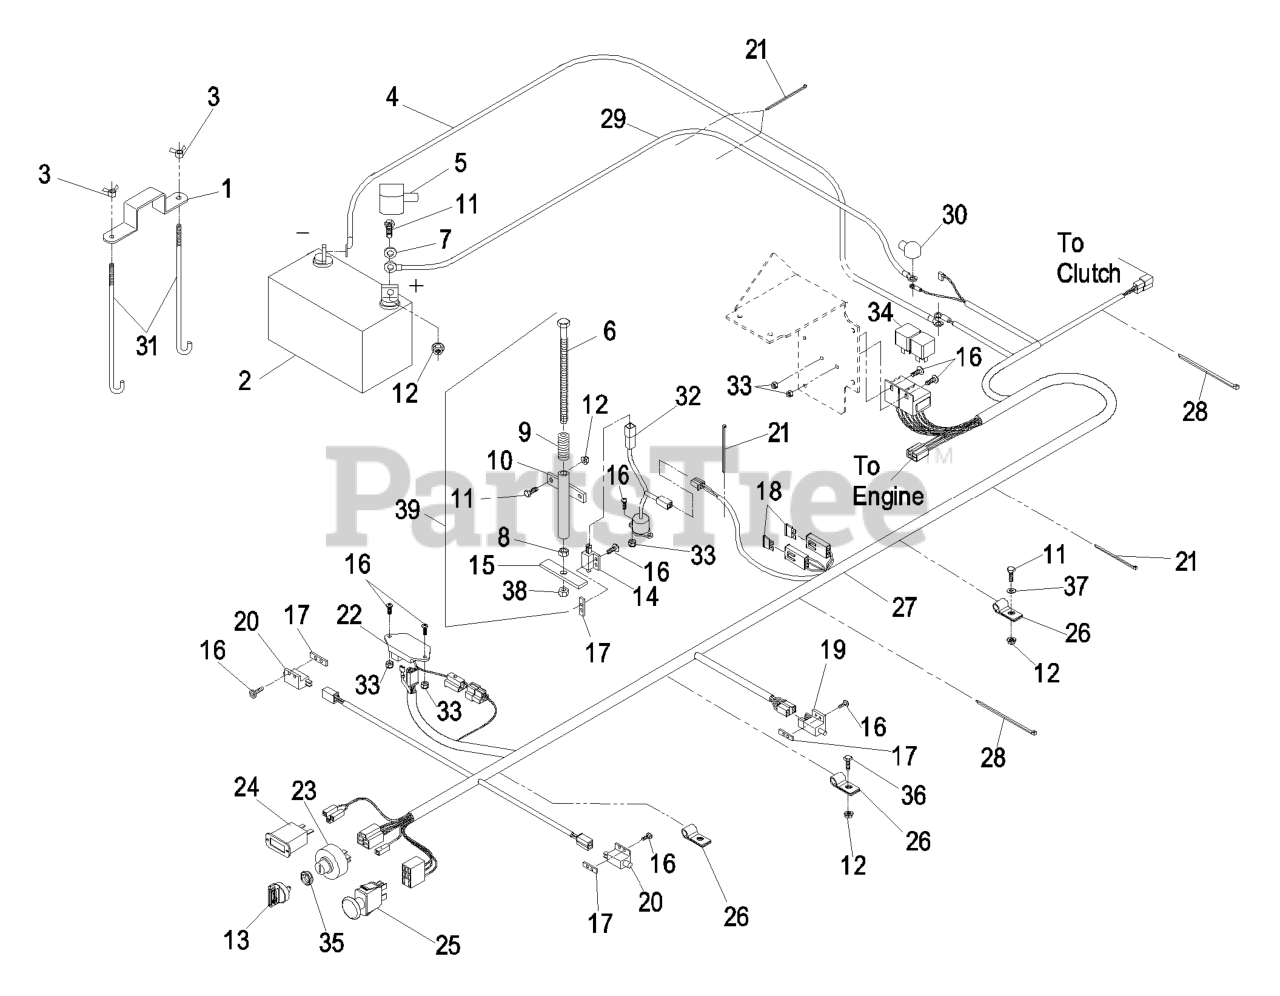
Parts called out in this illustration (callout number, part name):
1	STRAP-HOLDDOWN
3	WINGNUT
4	WIRE-GROUND
6	SCREW-HH
7	WASHER-FLAT
8	NUT-HEX
9	SPRING-SWITCH, SEAT
10	MOUNT-SPRING, SEAT
11	SCREW-HH
13	KEY-IGNITION
14	SWITCH-CLOSED, NORMALLY
15	PLATE-SWITCH, SEAT
16	SCREW-PPH
17	PLATE-TAPPED
18	FUSE-BLADE TYPE, 20 AMP
20	SWITCH-OPEN, NORMALLY
21	TIE-CABLE
22	MODULE-DELAY, SEAT
24	METER-HOUR
25	SWITCH-PTO
26	CLIP-LOOM
27	HARNESS,WIRE LAZER
28	TIE-PLASTIC
30	INSULATOR-SOLENOID
31	BOLT-HOLDDOWN
33	NUT-LOCK, NI
35	NUT-SWITCH, IGNITION
36	SCREW-HH
37	WASHER-FLAT
38	NUT-LOCK, NI
39	ASM,SEAT SWITCH ACTUATOR
